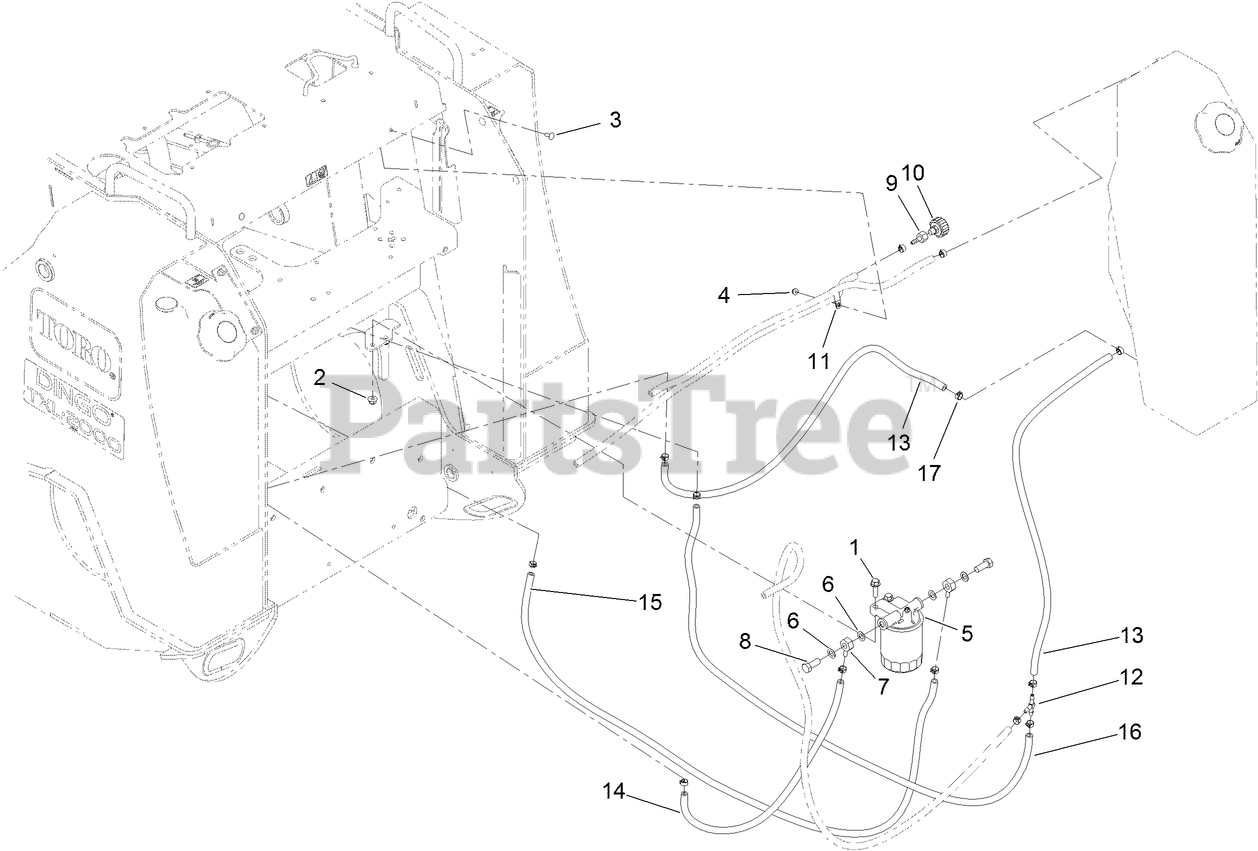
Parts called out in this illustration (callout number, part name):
1	SCREW-HHF
2	NUT-HF, NI
3	BOLT-CARR
4	NUT-HF
5	FILTER-FUEL
6	O-RING
7	ADAPTER-FUEL
8	SCREW-ADAPTER
9	FITTING-STRAIGHT
10	BREATHER
11	CLAMP-R, DOUBLE TUBE
12	FITTING-TEE, BARBED
13	HOSE-FUEL
14	HOSE-FUEL
15	HOSE-FUEL
16	HOSE-FUEL
17	CLAMP-HOSE
